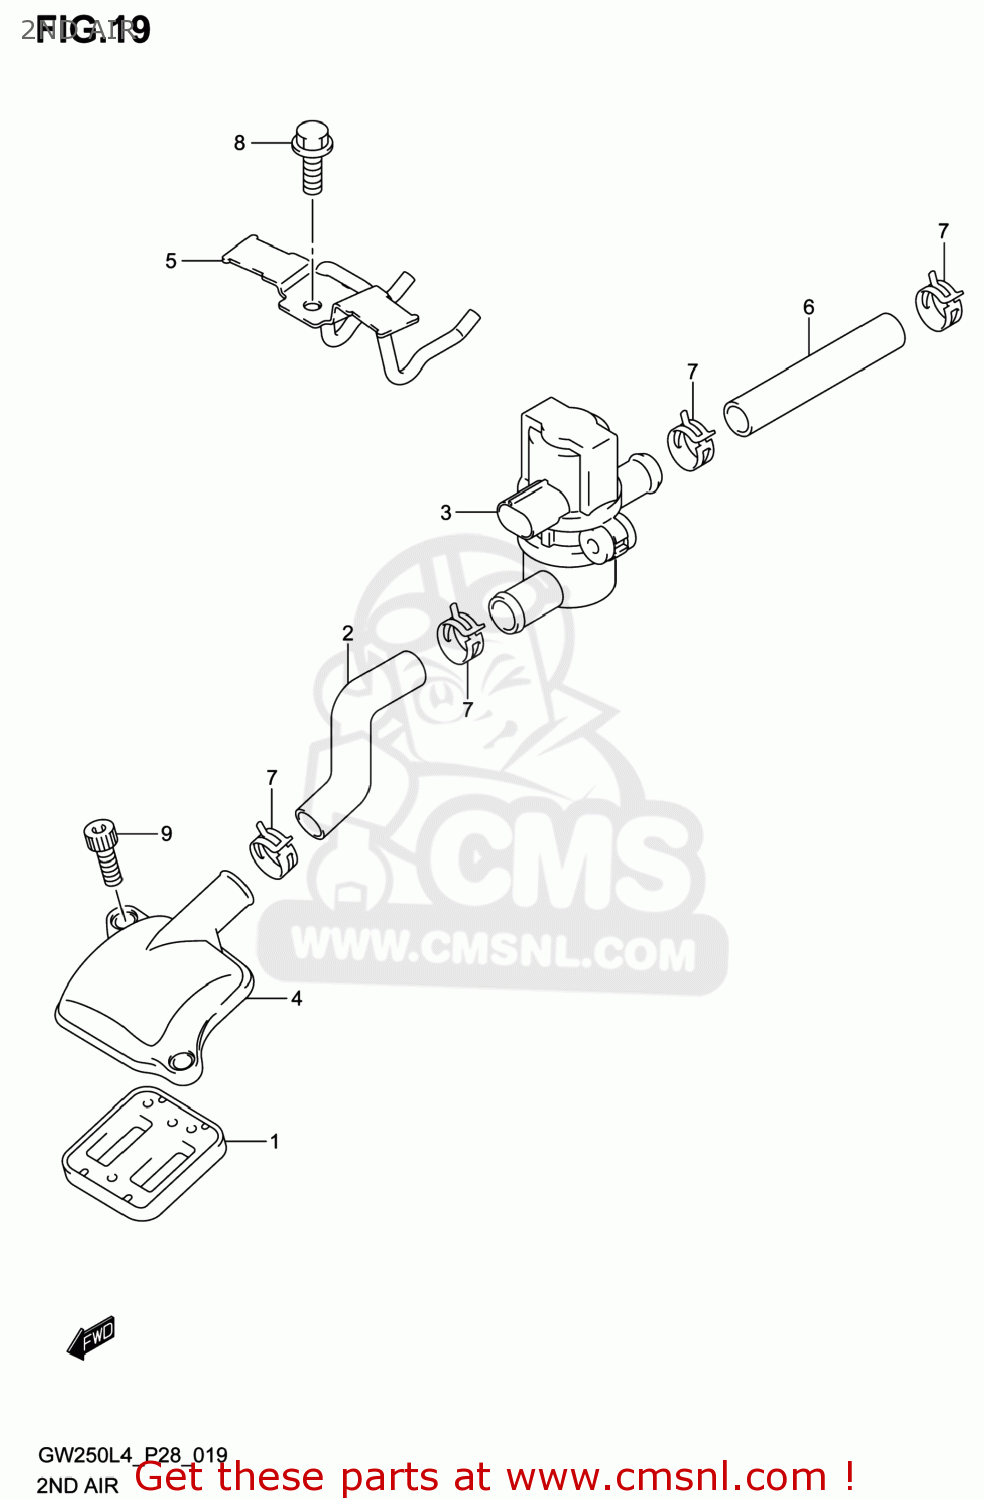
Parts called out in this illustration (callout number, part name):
1	VALVE ASSY,2ND AIR REED
2	HOSE,2ND AIR VALVE
3	VALVE ASSY,AIR CUT
4	COVER,2ND AIR REED VALVE
5	BRACKET,2ND AIR VALVE
6	HOSE,2ND AIR CLEANER
7	CLIP
8	BOLT
9	BOLT
